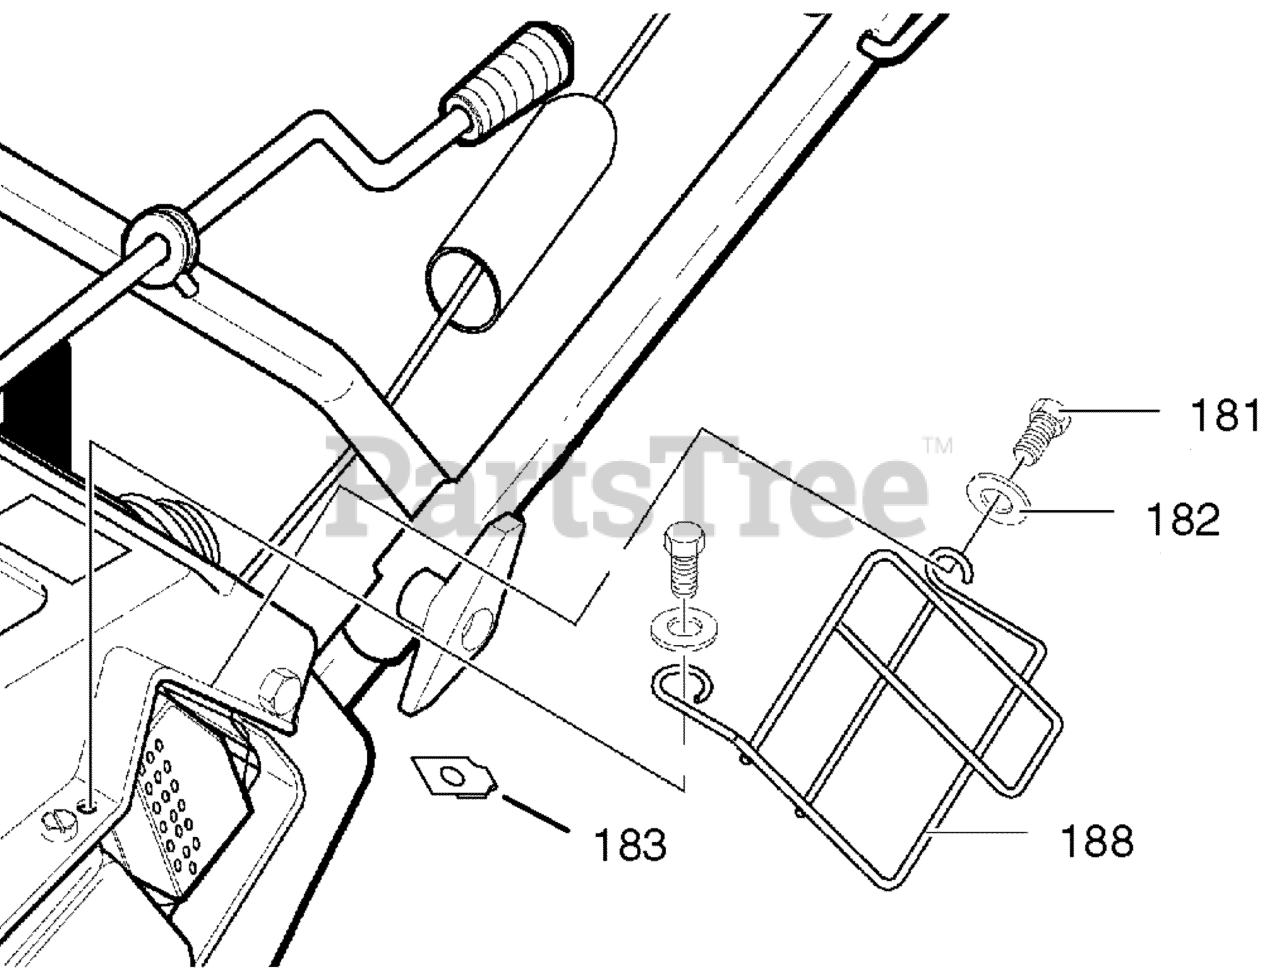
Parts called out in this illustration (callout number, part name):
181	SCREW
182	WASHER, FLAT
183	NUT, TINNERMAN 1/4-20
188	GUARD, MUFFLER -EXPT
